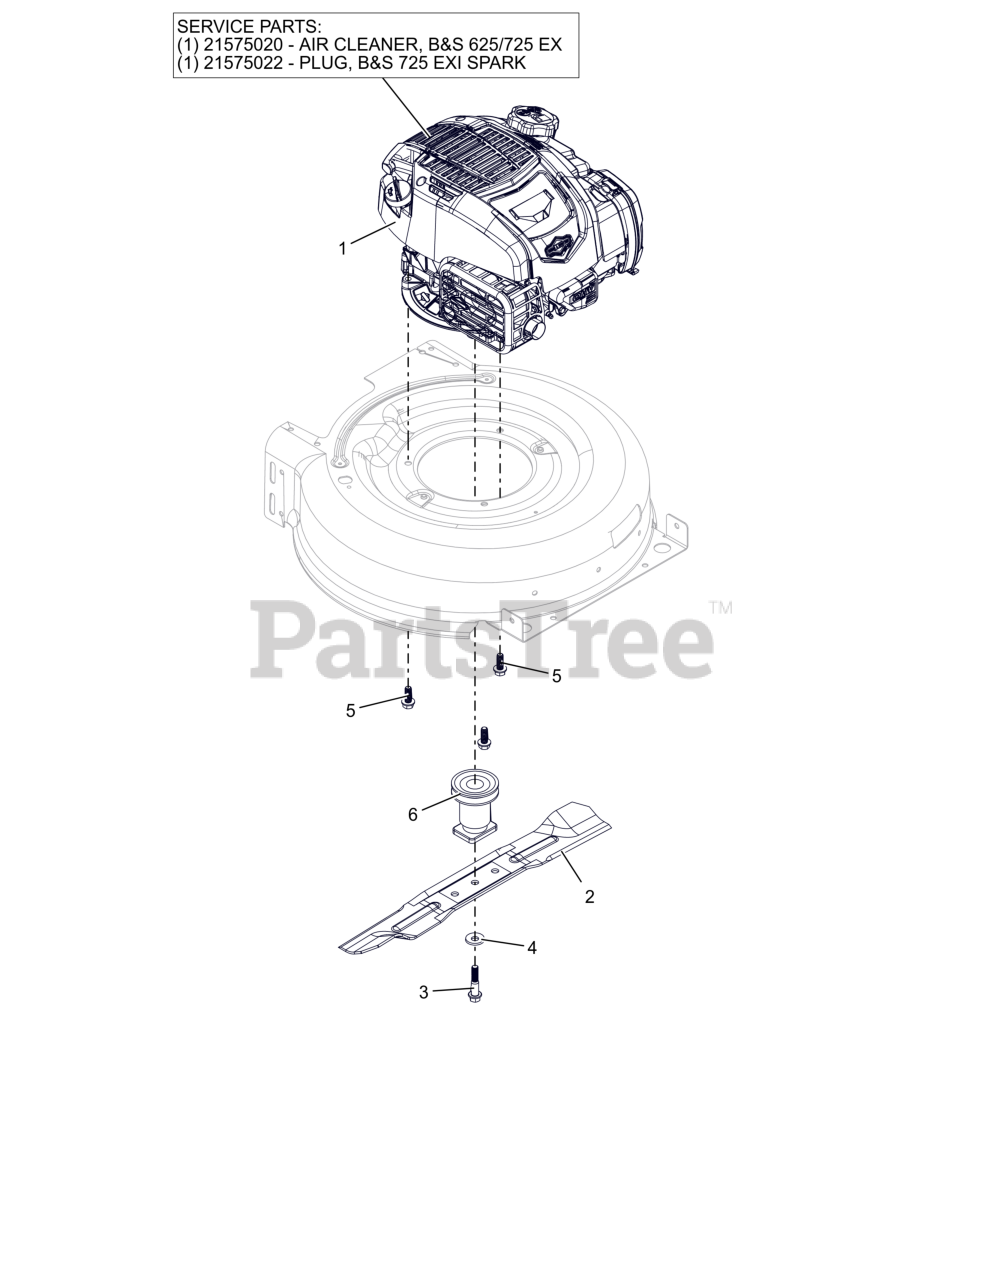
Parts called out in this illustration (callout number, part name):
1	ENGINE, BRIGGS 725 EXI
1	AIR CLEANER- B&S 625/725 EX
1	PLUG- B&S 725 EXI SPARK
2	BLADE, MOWER 21" HIGH LIFT
3	BLT-SHLDR .435X1.00X.38-24
4	WSHR, BLVL- .440X1.130X.120
5	SCR-TAP, 3/8-16X1.00 HWH
6	SPCR, BLADE - SINGLE
